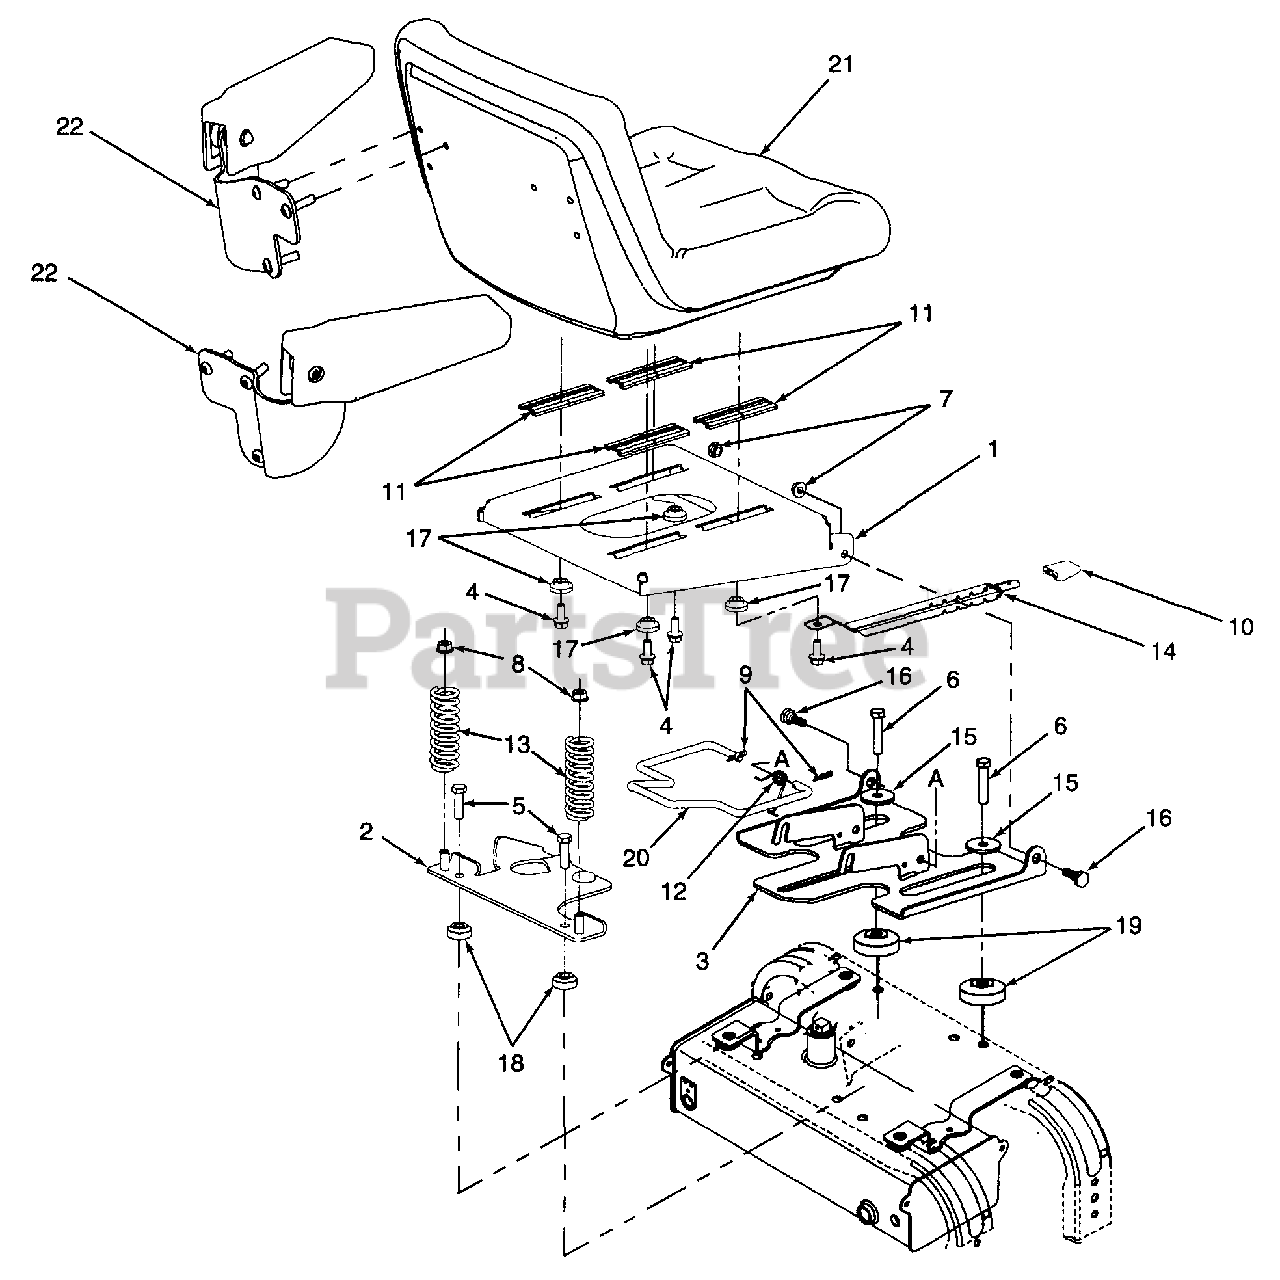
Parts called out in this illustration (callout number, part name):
1	Seat Base
4	Screw, Hex Wash Hd Tapp 5/16-18 x .75
5	Screw, Hex Cap 3/8-16 x 1.5 GR5
6	Screw, Hex Cap 3/8-16 x 1-3/4 GR5
7	Nut, Hex Flange Lock 5/16-18 GR5
8	Nut, Hex Flange Lock 3/8-16 GR5
9	Pin, Internal Cotter
10	Knob, Seat Adjustment
11	Seat Slide
12	Spring, Torsion
13	Spring, Compression
14	Spring, Index
15	Washer, Flat, .390 x 1.5 x .134
16	Bolt, Shoulder .437 x .268:5/16-18
17	Spacer, Shoulder, .38 I.D.
18	Spacer, Shoulder
19	Spacer, Seat Pan Shoulder
20	Rod, Seat Pan Lock
21	Seat Assembly
22	Seat Arm
